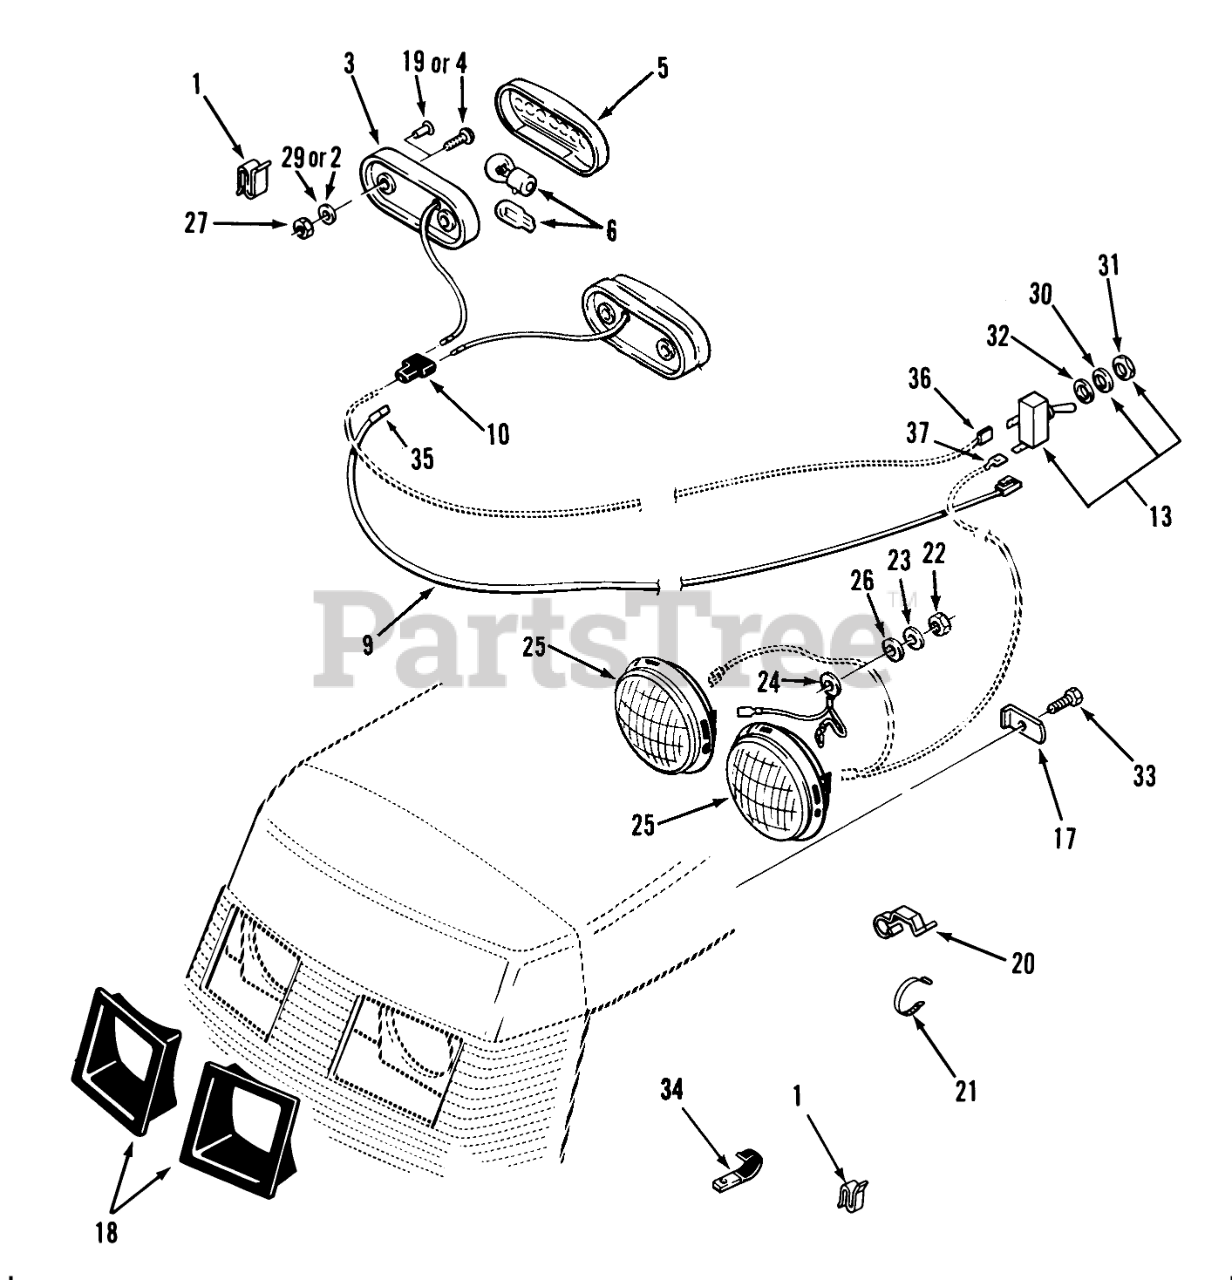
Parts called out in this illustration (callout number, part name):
1	SPEED CLIP
2	Lockwasher
3	BASE-TAIL LIGHT
4	Screw
5	LENS-TAIL LIGHT
6	Bulb
9	WIRE TAIL LIGHT
10	CONNECTOR 3 WIRE
13	SWITCH-LIGHTS
17	LOCK-HEADLIGHT
18	HEADLIGHT BEZEL ASSY.(SERVICE)
19	RIVET-4
20	CLIP-WIRE
21	PLASTIC TIE
22	Nut
23	Washer-Lock
24	LIGHT GROUND WIRE
25	HEAD LAMP
26	WASHER 5/16 SAE
27	Nut
29	WASHER
30	TAB-WASHER
31	NUT-HEX
32	Washer
33	Bolt
34	CLIP
35	Sur-Plug
36	TERMINAL 10
37	Terminal
